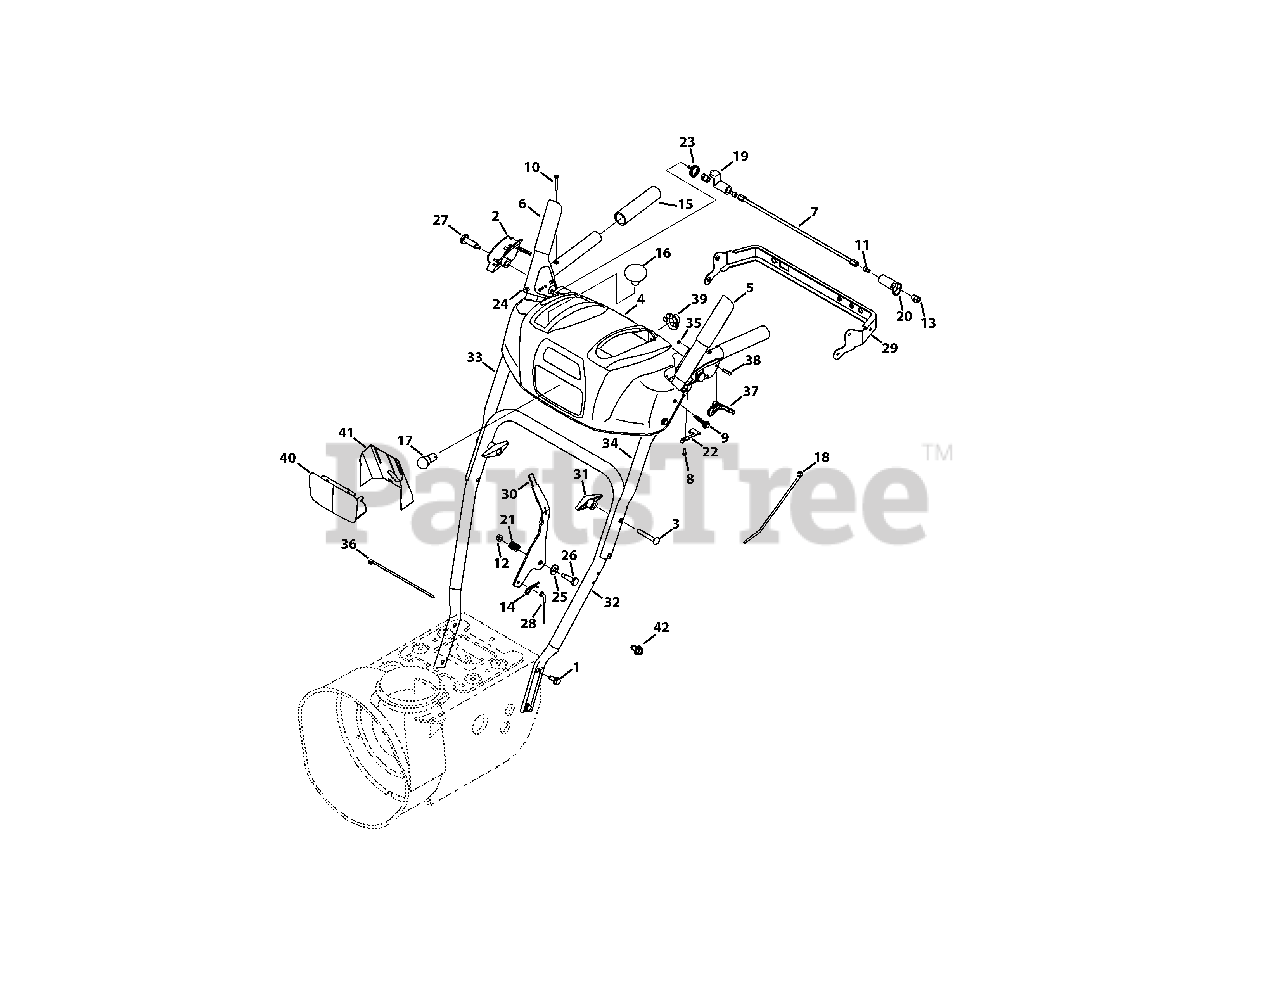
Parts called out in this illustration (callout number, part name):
1	Hex Screw, 5/16-18 x .750
2	Handle Clutch Lock LH Assy
2	Handle Clutch Lock RH Assy
3	Carriage Screw, 5/16-18 x 2.25
4	Handle Panel, includes Ref. 40 & 41
5	Handle Engagement Assembly LH
6	Handle Engagement Assembly RH
8	Screw, 8-16 x 0.50
9	Screw, 1/4-20 x 1.625
10	Screw, 10-24 x 1.375
11	Socket Screw, 1/4-20 x .50
12	Flange Lock Nut, 1/4-20
13	Shoulder Nut, 1/4-20
14	Click Pin, .092 x 1.64
15	Handle Grip
16	Shift Knob
18	Cable Tie
20	Clutch Lock Cam
21	Compression Spring
22	Clutch Lock Spring
23	Torsion Spring
24	Rubber Bumper
25	Flat Washer, .385 x .87 x .06
26	Shoulder Screw, .374 x 1.05
27	Shoulder Screw, 1/4-20 x 1.345
28	Speed Cable Selector
30	Shift Lever
31	Wing Knob
32	Lower Handle
33	Upper Handle RH
34	Upper Handle LH
36	Cable Tie
37	Clutch Trigger
39	Light Socket
41	Lens Label
42	Screw, TT, 1/4-20 x .500 (For ground wire)
